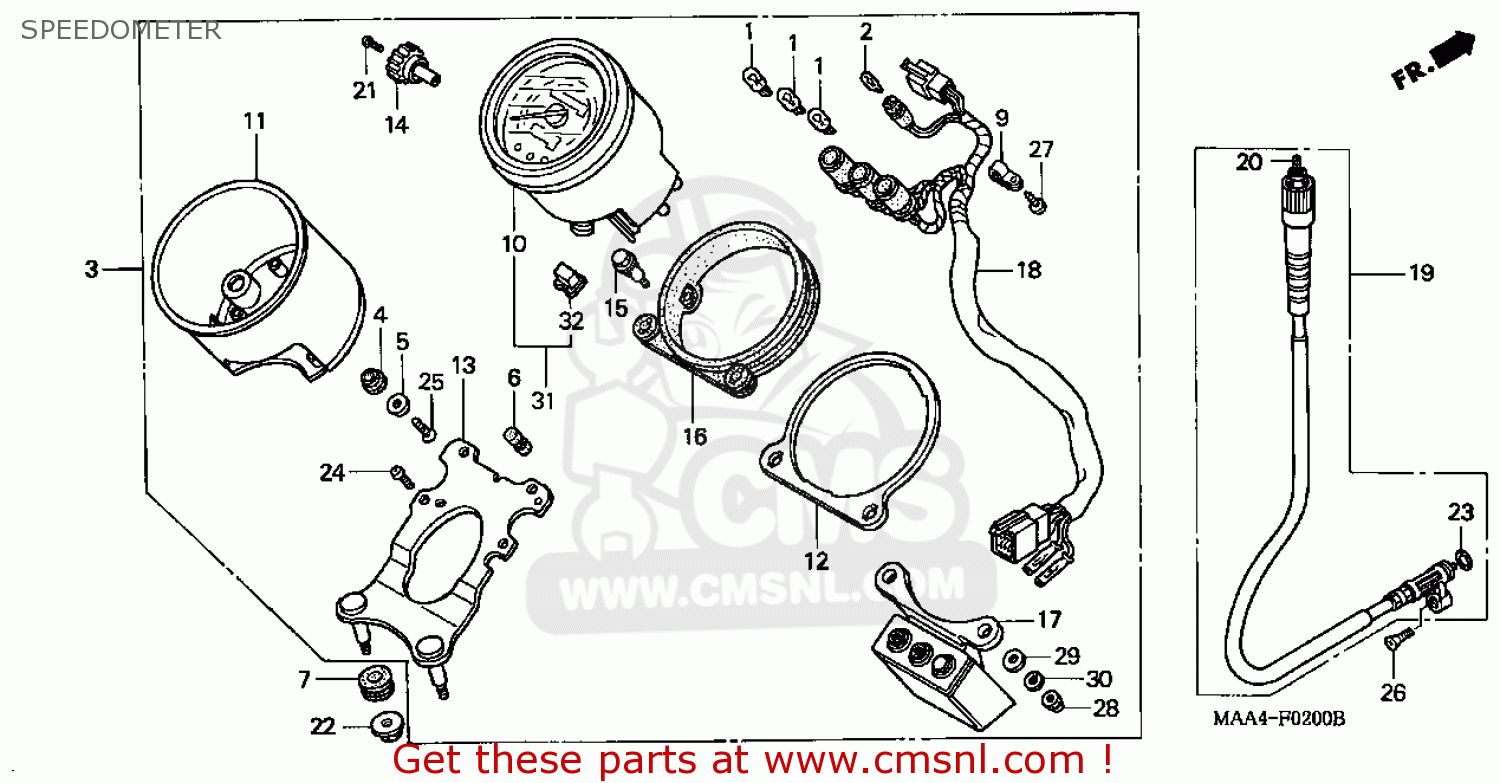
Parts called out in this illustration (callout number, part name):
1	BULB
2	BULB WEDGE BASE T
3	METER ASSY,COMB
4	RUB.,METER,SET
5	WASHER
6	MOUNT RUBBER
7	RUB,METER MOUNT
9	CLAMP
10	SPEEDOMETER ASSY
11	COVER METER
12	SETTING PLATE
13	BRACKET COMP
14	KNOB
15	BOLT SET(P.BOX)
16	CUSHION RUBBER
17	PILOT BOX ASSY
18	SOCKET COMP
19	CABLE ASSY,SPDMT
20	CABLE,INNER
21	SCREW PAN.2X6
22	NUT,FLANGE,6MM
23	ORING,6.8X1.9
24	SCREW,PAN,4X8
25	SCREW,OVAL, 4X8
26	SCREW,OVAL,5X20
27	SCREW,TAPPING,4X12
28	NUT,HEX.,CAP,5MM
29	WASHER,PLAIN,5MM
30	WASHER,SPG.,5MM
32	GROMMET
